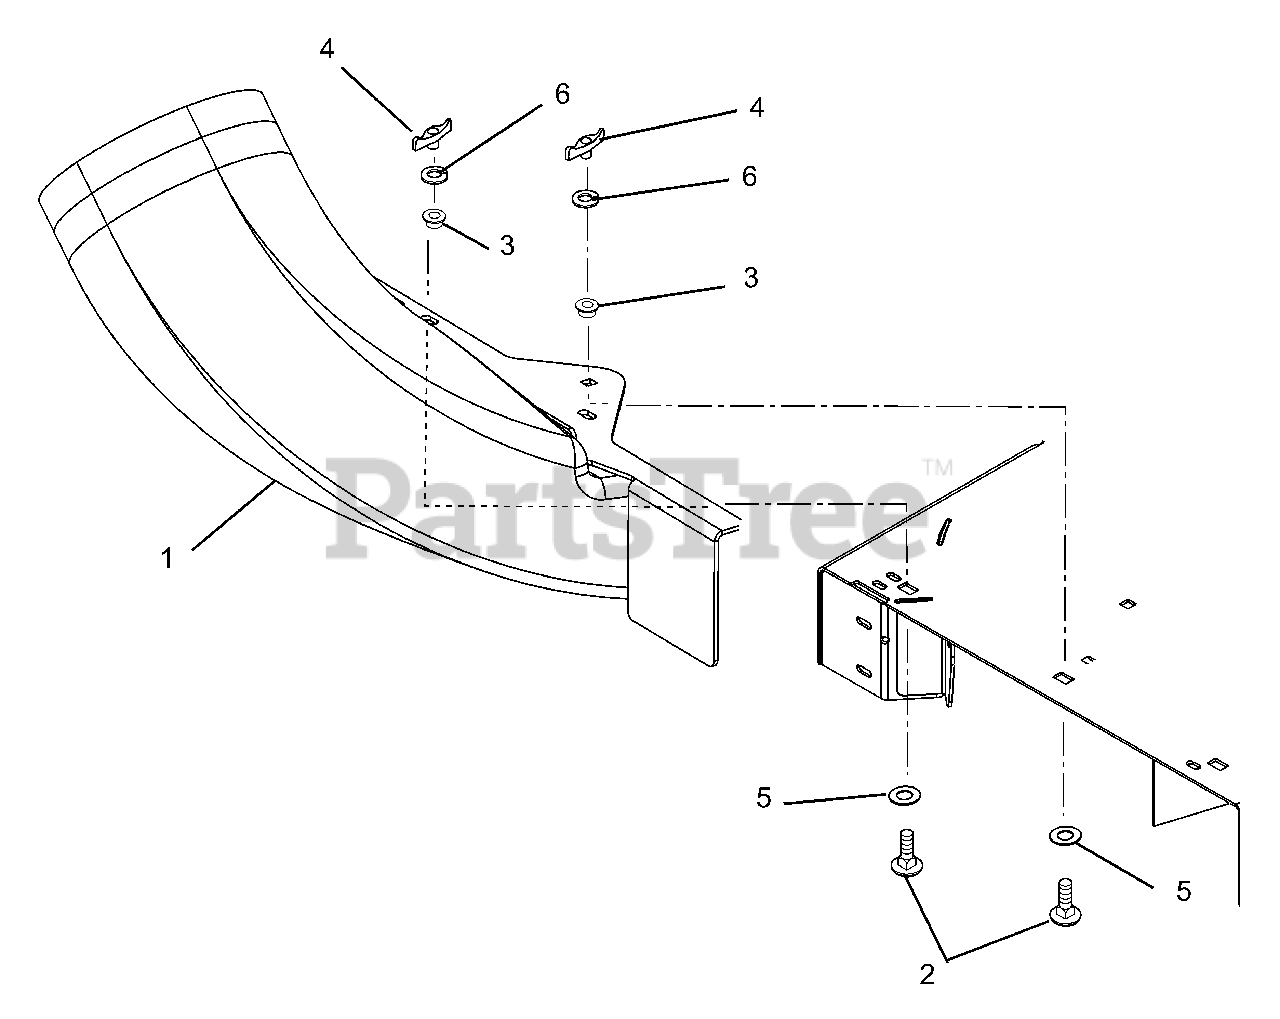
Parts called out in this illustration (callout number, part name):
1	Boot Assembly
2	Bolt-Round Head Square Neck .375-16 x 1.0
3	Push Nut, .375
4	Nut, Wing .375-18
5	Washer, Flat Steel .52 x .827 x .062
6	Washer-Locking .375 x .115 Heavy
